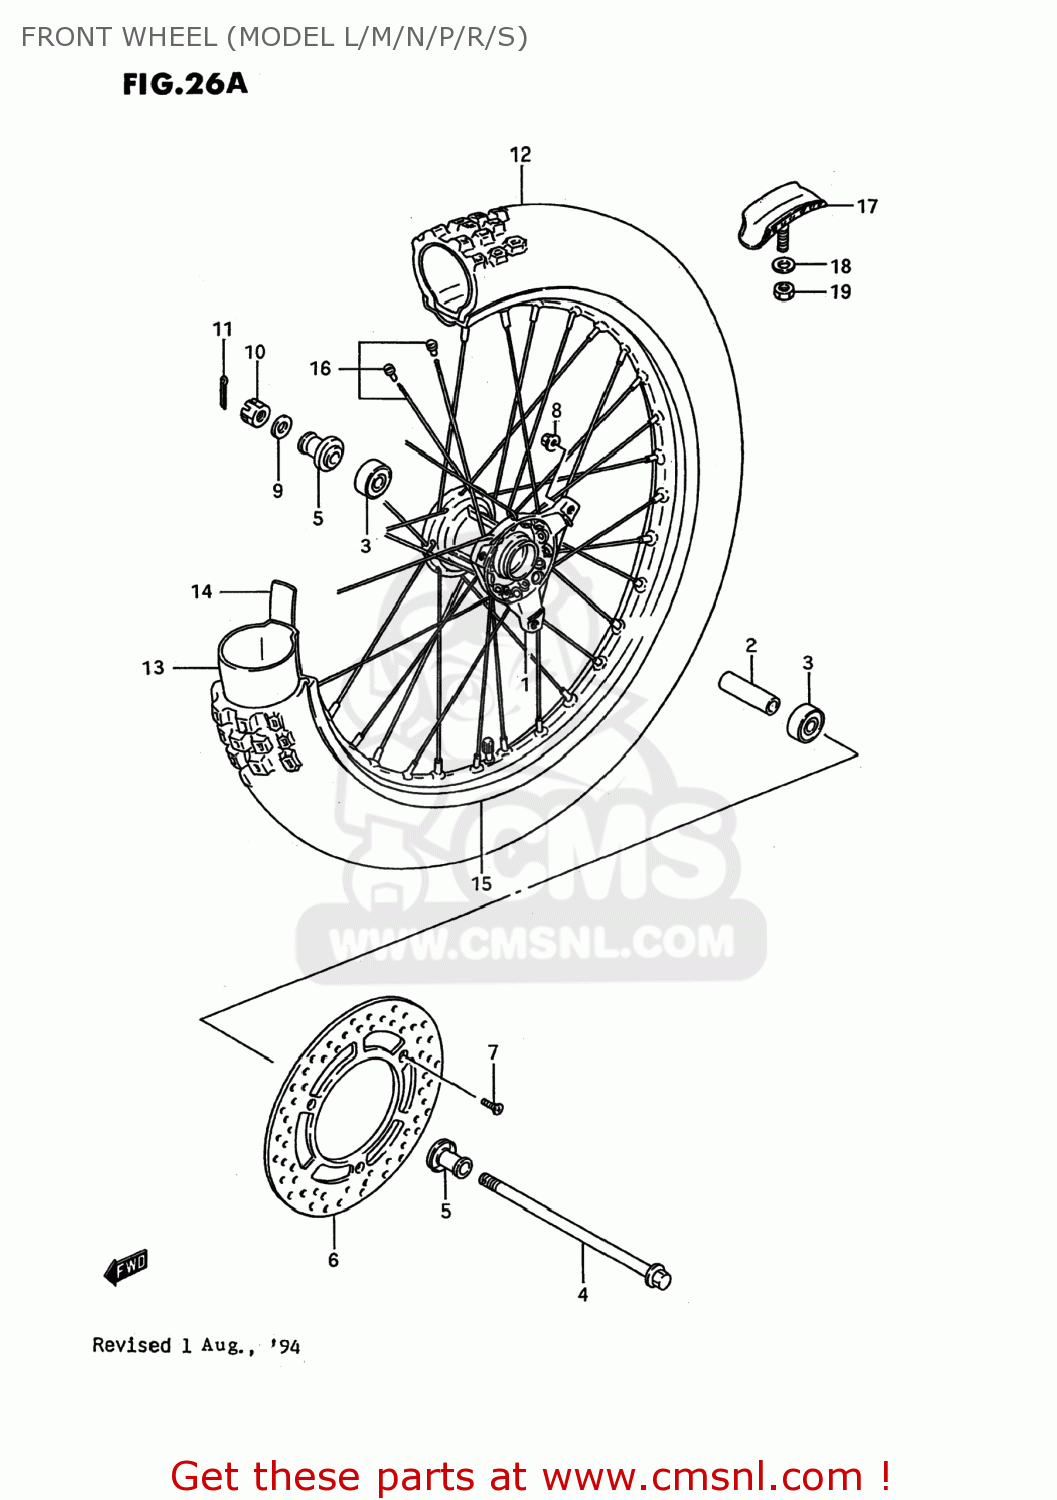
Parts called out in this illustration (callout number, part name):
1	HUB,FR WHEEL
2	SPACER,FR HUB BEARING
3	BEARING (12X32X10)
4	AXLE,FR
5	SPACER,FR AXLE
6	DISC,FRONT BRAKE
7	SCREW(6X22)
8	NUT
9	WASHER
10	NUT, REAR AXLE
11	PIN 20X20
12	TIRE,FRONT
13	TUBE,INNER
14	PROTECTOR,WHL INR TUBE
15	RIM,FR WHEEL(1.40X17)
16	SPOKE SET,FR WHEEL
17	STOPPER,BEAD
18	WASHER
19	NUT
